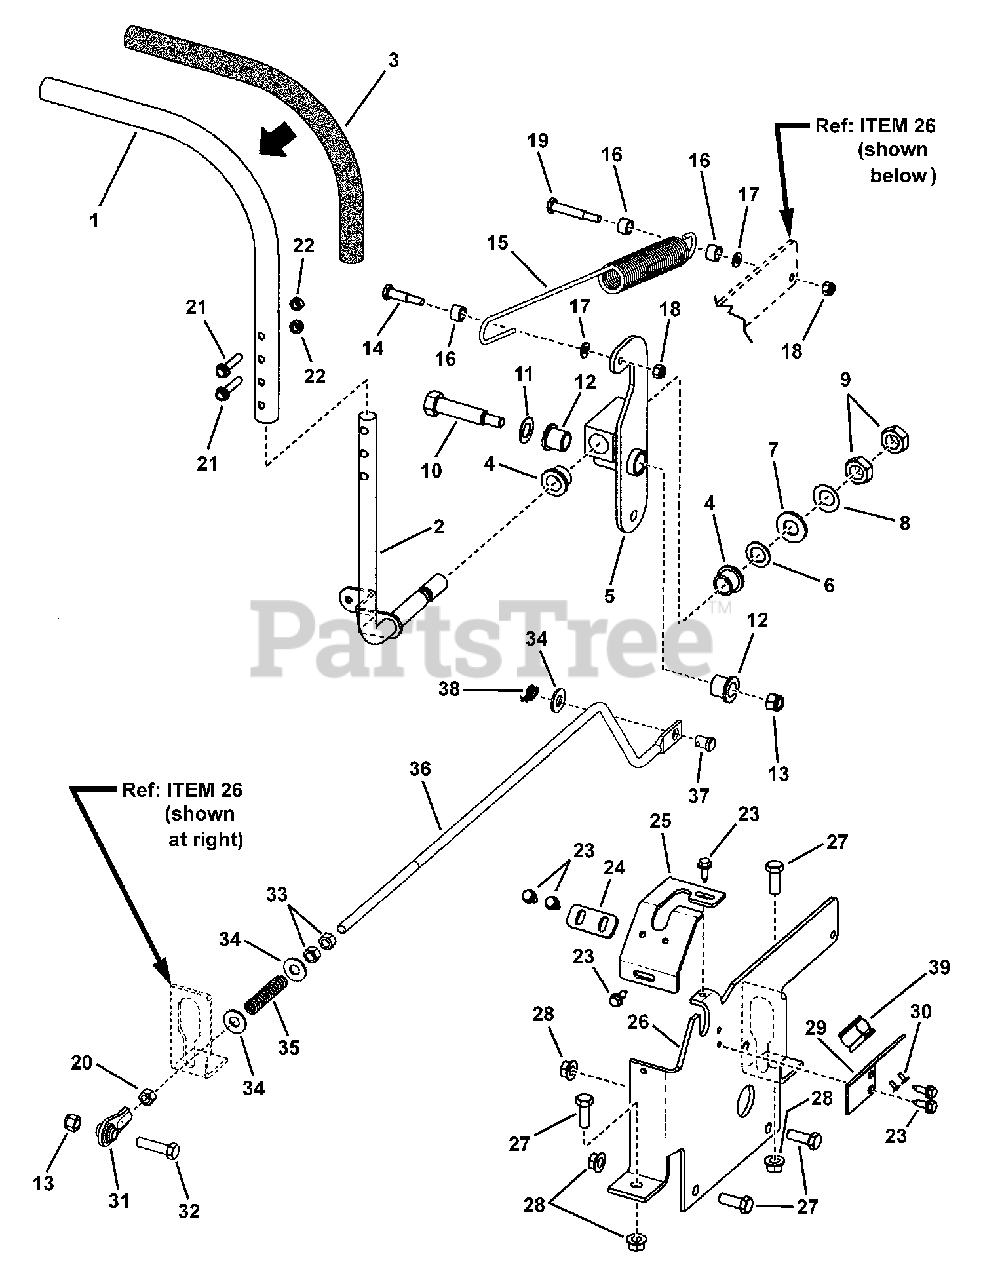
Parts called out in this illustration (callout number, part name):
1	HANDLE
2	WELDMENT, LH Control Arm (5/8" dia. Rod)
3	FOAM GRIP, Handle
4	BUSHING, Bronze, 5/8 x 5/8"
5	WELDMENT, Control Arm, LH
6	WASHER, 5/8 ID x 1.00 OD x .065 Nylon
7	WASHER, 5/8" Flat SAE
8	WASHER, .64 x 1.12 x .028 Beveled
9	NUT, 5/8-18 Hex Jam
10	SHOULDER BOLT, 3/8-16
11	THRUST WASHER, .562 ID x 1.000 OD x .030/.032 Thick
12	FLANGE BEARING, 9/16 I.D. P.M.
13	NUT, 3/8-16 Hex Nyloc
14	SHOULDER BOLT, 5/16 x 1/4-20
15	SPRING, Extension, RTN, ERZT
16	SPACER, 9/16" OD x 12GA x .325
17	WASHER, 1/4" I.D. Flat
18	NUT, 1/4-20 Hex Nyloc
19	SHOULDER BOLT, 5/16 x 1/4-20
20	NUT, 3/8-24 Hex Jam
21	SCREW, 1/4-20 x 1-1/4" Hex Head Cap, GR 5
22	NUT 1/4-20 Hex Center Lock, GR 5 YZ
23	SCREW, 1/4-20 x 3/4" Hex Washer Self-Tap
24	PLATE, Fwd/Rev Adjust
25	TRACK, Control Stick, L.H.
26	CONTROL BRACKET, LH
27	SCREW, 3/8-16 x 1" Hex Head Cap, GR 5, YZ
28	NUT, 3/8-16 Hex Flange Lock
29	BRACKET, Rod Holder, RZT
30	POP RIVET, 1/8 x 3/8"
31	ROD END
32	SCREW, 3/8-16 x 1-1/2" Hex Head Cap, GR 5
33	NUT, 3/8-24 Hex, GR B, YZ
34	WASHER, 7/16" Flat
35	SPRING, Compression (Brake)
36	ROD, Link Fwd./Rev. (3/8-24 thread)
37	CLEVIS PIN, 7/16 x 1"
38	COTTER PIN, 1/2 Self Locking, YZ
39	CLIP, Spring
